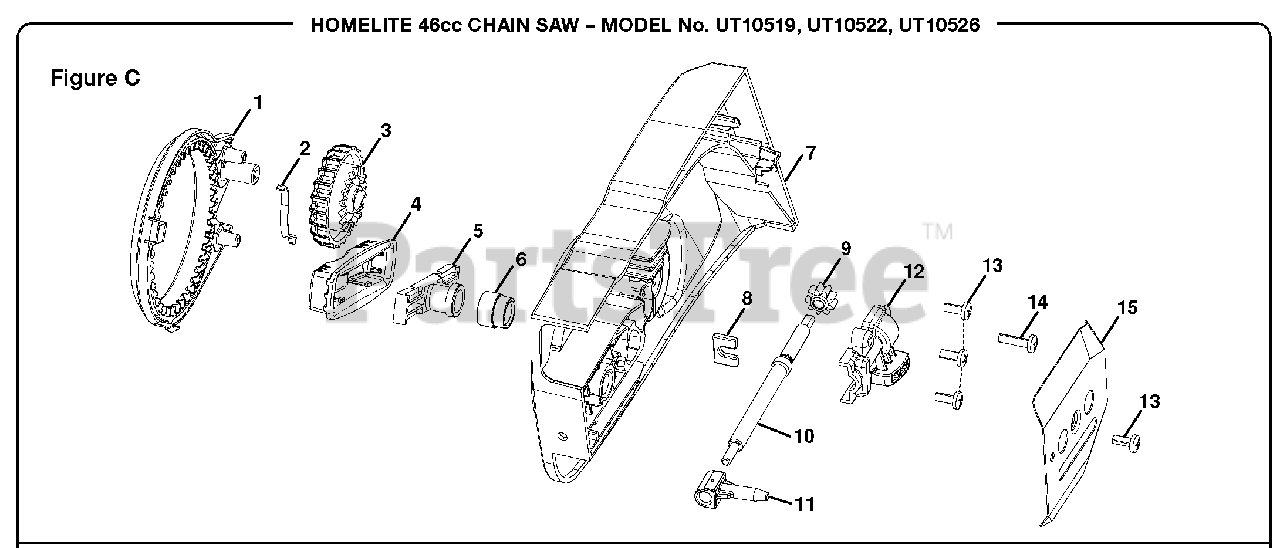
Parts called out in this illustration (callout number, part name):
1	Clutch Cover Ring
2	Lock Spring Plate
3	Adjustment Knob
4	Cover Knob
5	Tension Nut
7	Clutch Cover
8	Thrust Washer
9	Chain Adjustment Gear
10	Adjustment Rod
11	Adjustment Pin
12	Gear Cover
13	Screw (6-19 x 8 mm)
14	Screw (6-19 x 1/2 in.)
15	Guide Bar Plate
